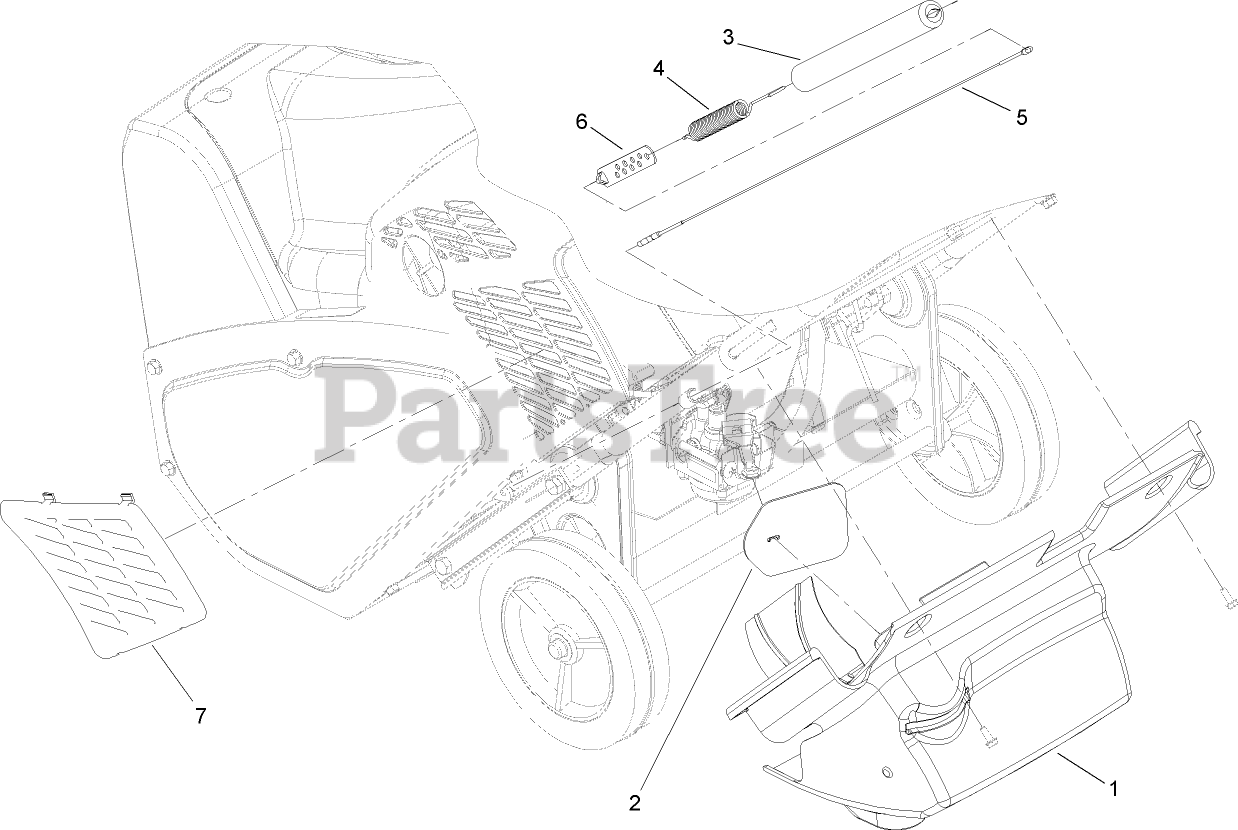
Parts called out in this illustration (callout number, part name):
1	LOWER SHROUD ASM (only on: 38515, 38516, 38517, 38518)
1	LOWER SHROUD ASM, CE (only on: 38535, 38536, 38537, 38538)
2	SHIELD-HOLE, CHOKE
3	COVER-SPRING
4	SPRING-EXTENSION
5	CABLE-CLUTCH
6	ADJUSTER-CABLE, CLUTCH
7	COVER-SHIELD, HEAT
